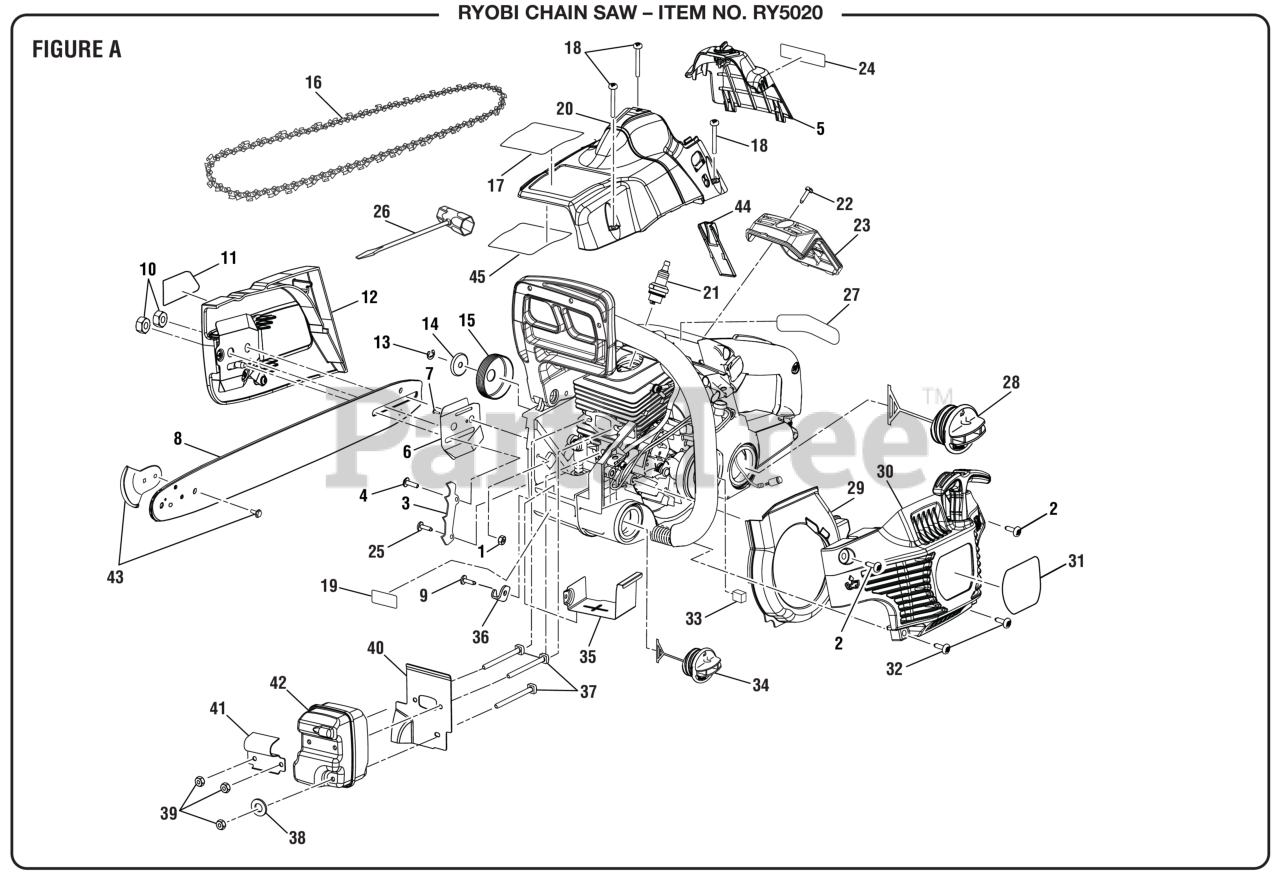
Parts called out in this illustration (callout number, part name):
1	LOCK NUT, HEX (10-24)
2	Screw, Truss Hd., Plastite (10-14 x 5/8")
3	BUMPER SPIKE
4	Screw (10-24 x 5/8 in., Torx Pan Hd.)
5	Filter Cover
6	Inner Guide Plate
7	Screw (#6-19 x 1/2 in., Phillips Hd. T.F.)
8	20 in. Guide Bar w/SAFE-T-TIP
9	Screw (10-14 x 1/2 in., Torx Truss Hd. T.F.)
10	Hex Nut (5/16-18 Flange)
11	Logo Label
12	Chain Cover Assembly
13	RING, RETAINING
14	Cupped Washer
15	Sprocket Drum and Bearing Assembly (.325 chain)
16	Chain (.325 x 78 links, 20 in.)
17	Warning Label
18	Screw (10-16 x 1-1/2 in. Special)
19	Warning Label (Combustion)
20	Cylinder Housing
21	SPARK PLUG CHAMPION - RCJ-6Y
22	Screw-Slotted Pan Hd. (8-16 x 5/8")
23	Air Filter 50cc
24	Chain Replacement Label
25	Vacuum Tube Screw (10-14 x 1/2 in., T25 Torx Truss Hd. T.F.)
26	Combination Wrench
27	Starting Instruction Label
28	Fuel Cap Assembly
29	Fan Housing Baffle
30	Starter Cover Assembly
31	Logo Label (Item No. RY5020)
32	Screw, Truss Hd., Plastite (10-14 x 7/8")
33	PRE FILTER
34	Oil Cap Assembly
35	Heat Shield
36	Chain Catcher
37	Muffler Bolt (Square Hd.)
38	Washer (OD16 x ID5.5 x 1.5t)
39	NUT-LOCKING HEX (10-32)
40	Muffler Gasket
41	Muffler Deflector
42	Muffler Assembly
43	SAFE-T-TIP and Screw Assembly (.325 Bar)
44	Cylinder Housing Divider
45	Heat Reflector Tape
